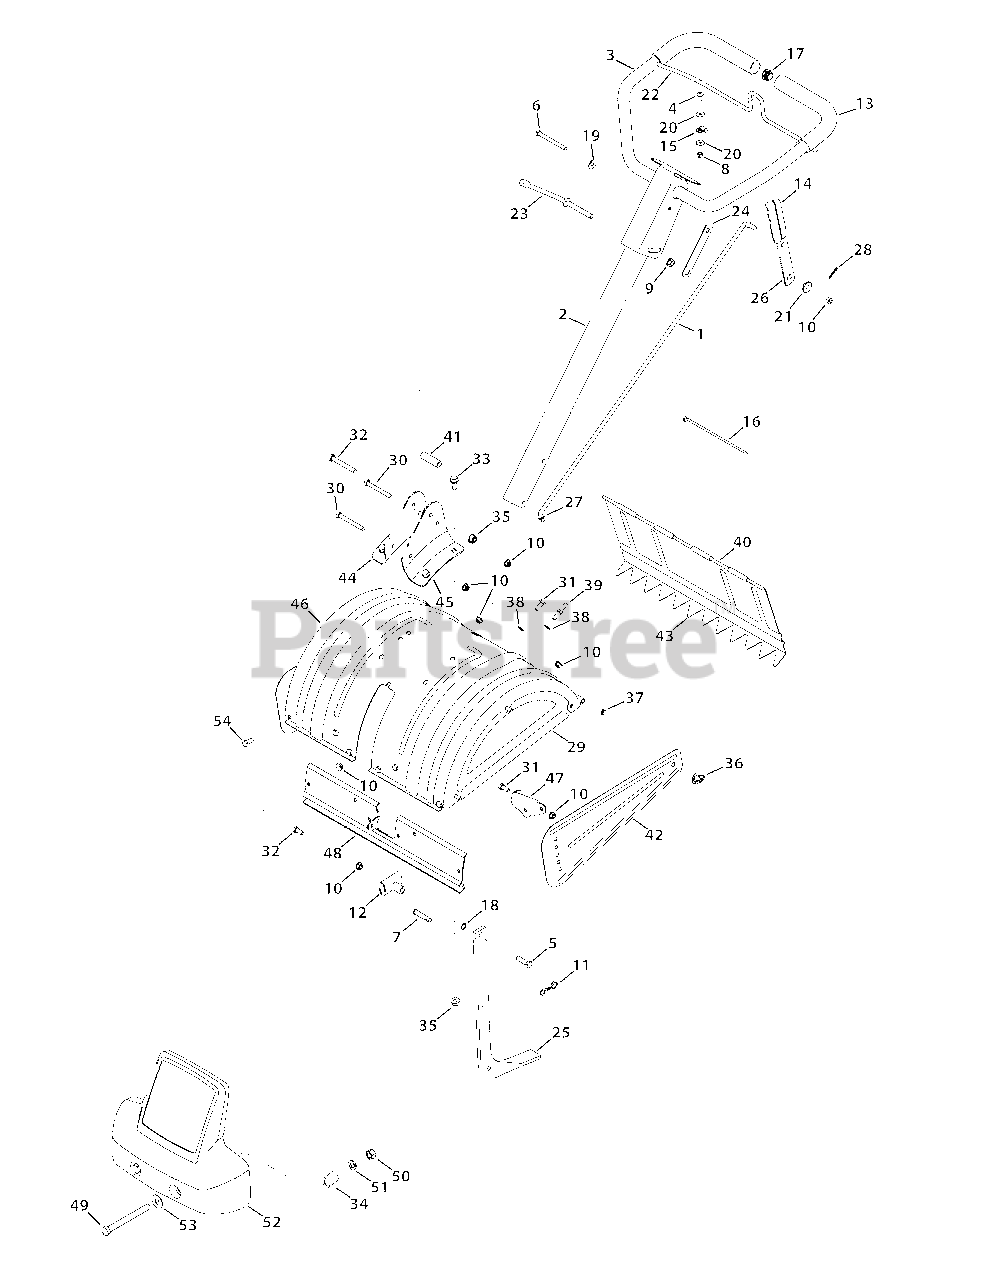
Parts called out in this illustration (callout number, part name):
1	Shift Rod
2	Lower Handle Tube Assembly
3	Upper Handle Assembly
4	Screw, 1/4-20 x 0.625
5	Hex Screw, 3/8-16:1.25
6	Hex Screw, 5/16-18 x 3.25
7	Clevis Pin, .375 X 1.75
8	Hex Lock Nut, 1/4-20
9	Flange Lock Nut, 3/8-24
10	Hex Lock Nut, 5/16-18
11	Cotter Pin
12	Small Tee Knob
13	Foam Grip, .970 x 11.0
14	Grip, .1875 x 1.00
15	Battery Clamp, 5/16
16	Cable Tie, 8.5
17	End Plug
18	Flat Washer, .385 x .620 x .033
19	Bell Washer, .340 x .872 x .060
20	Flat Washer, .260 x .720 x .060
21	Spacer, .50 x .190 x .360
22	Clutch Bail
23	Handle Adjustment Crank
24	Hex Nut Retainer Bracket
25	Tiller Depth Control
26	Shaft Rod Lever
27	Washer, .33 x .87 x .125
28	Cotter Pin, .072 x 1.12
29	End Cover Assembly
30	Hex Screw, 5/16-18 x 2.75
31	Hex Screw, 5/16-18 x 1.00
32	Hex Screw, 3/8-16 x 2.75
33	Hex Flange, 3/8-16 x .875
34	Hub, .636 x 1.00 x .94
35	Flange Lock Nut, 3/8-16
36	Wing Nut, 5/16-18
37	Speed Nut Cap, 1/4
38	Flat Washer, .344 x .62 x .033
39	Screw, Hex, 5/16-18 x .75
40	Tiller Flap Rod
41	Spacer, .322 x .625 x 2.00
42	Side Shield
43	Rear Tine Shield
44	RH Handle Mount Bracket
45	LH Handle Mount Bracket
46	Tine Shield
47	FRT Tine Shield Bracket
48	FRT Tine Shield Spacer Bracket
49	Hex Screw, 1/2-20 x 5.50
50	Hex Lock Nut, 1/2-20
51	Flat Washer, 1/2 x 1.25 x .10
52	Counterweight
